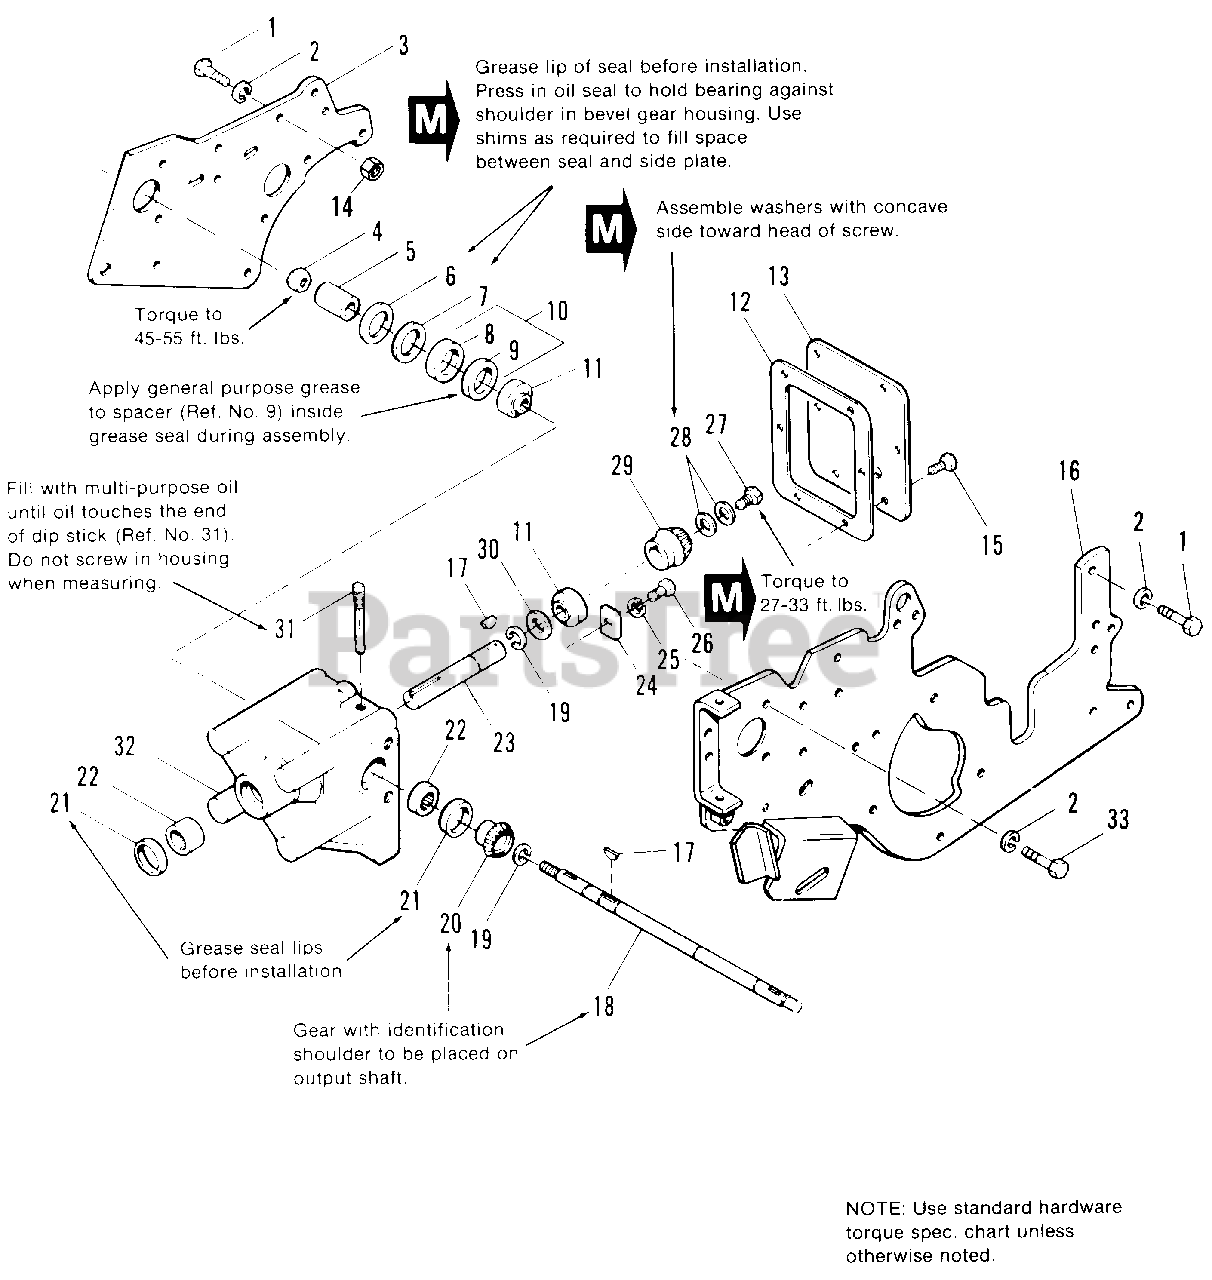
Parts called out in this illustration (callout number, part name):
1	CAPSCREW, Hex Hd., 7/16-14 x 1-1/4
2	LOCKWASHER, 7/16
3	PLATE, Side, RH
4	LOCKNUT, Hex, Jam, 3/4-16
9	SPACER, Seal, Oil
10	REPAIR KIT, Seal
11	BEARING, Ball
14	NUT, Hex, 7/16-14 x 1
15	CAPSCREW, Hex Hd., 1/4-20 x 5/8
16	PLATE ASSY, Side, LH
17	KEY, Woodruff, #9
18	SHAFT, Driven
19	RING, Retaining
20	GEAR, Bevel, Driven
22	BEARING, Needle
23	SHAFT, Driver
24	PLATE, Bearing, Clamp
25	LOCKWASHER, 5/16
26	CAPSCREW, Hex Hd., 5/16-18 x 5/8
27	CAPSCREW, Hex Hd., 5/16-18 x 3/4
29	GEAR, Bevel, Driver
32	HOUSING, Bevel Gear
33	CAPSCREW, Hex Hd., 7/16-14 x 1
